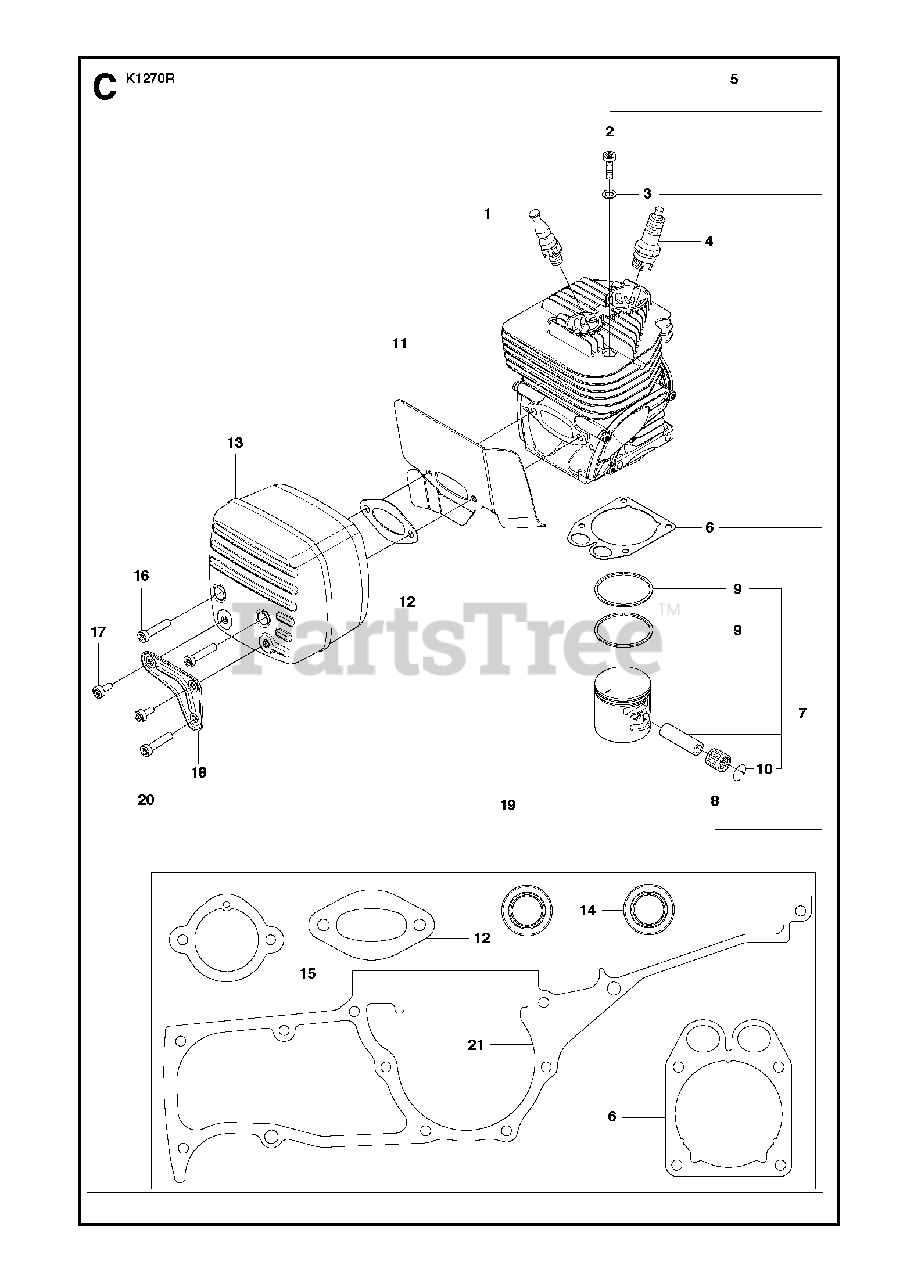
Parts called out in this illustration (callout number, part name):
5	CYLINDER ASSYIncl. 2, 3, 6 - 8
7	PISTON ASSYIncl. 9 - 10
8	NEEDLE HOLDER
13	MUFFLER ASSYIncl. 14 - 15
14	SEALING RING
17	SCREW ITXSCM
20	SCREW ITXSCM
